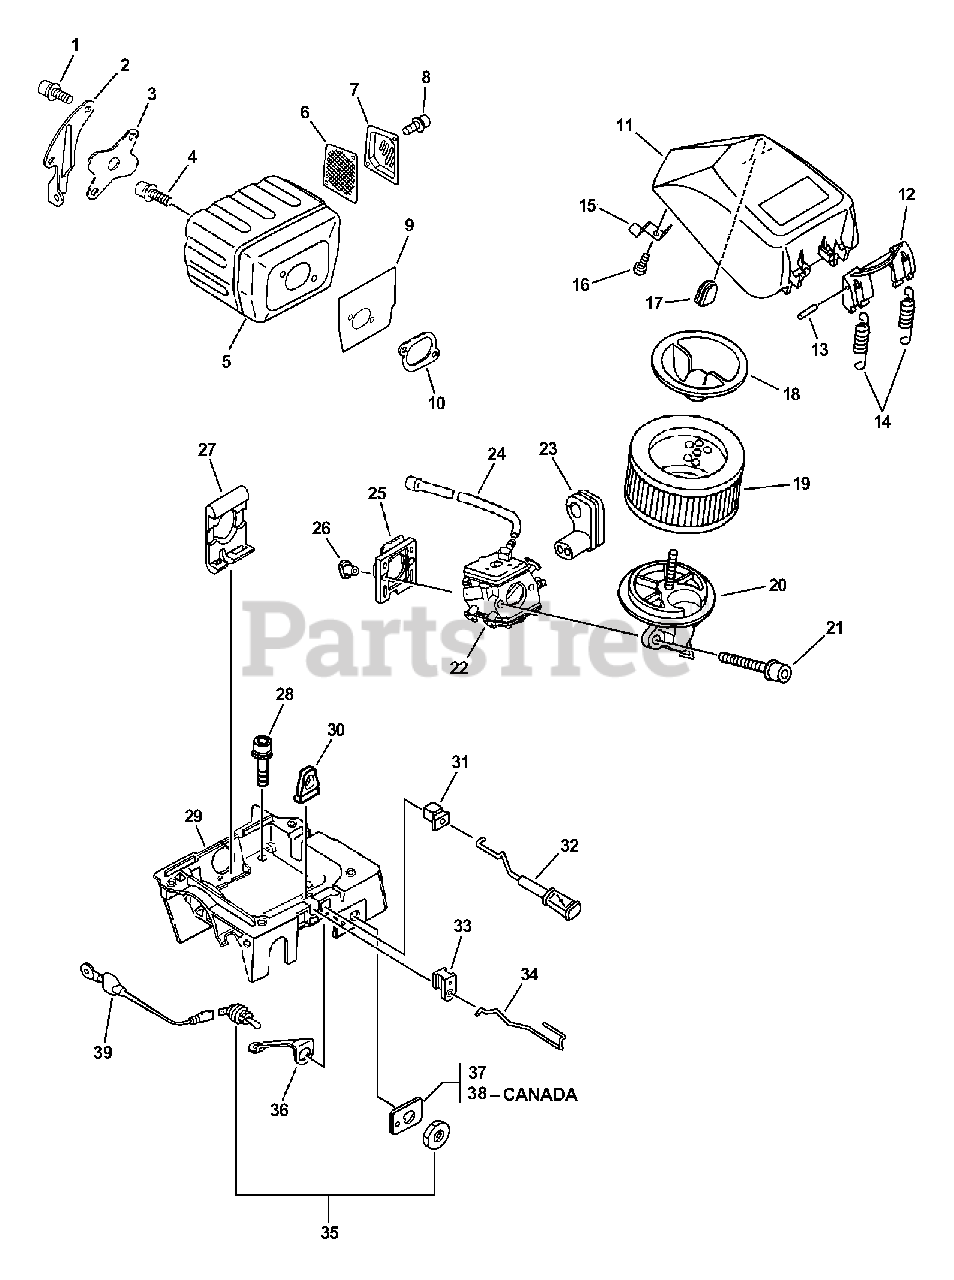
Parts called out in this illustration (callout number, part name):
1	SCREW - 5X14
2	BRACKET, MUFFLER
3	COVER, MUFFLER
4	SCREW - 5X20
5	MUFFLER
6	SCREEN, SPARK ARRESTOR
7	GUIDE, EXHAUST
8	SCREW - 4X10
9	SHIELD, EXHAUST
10	GASKET, EXHAUST
12	COVER, AIR FILTER
13	PIN - 3X12
15	SPRING, FLAT
16	SCREW - 4X10
18	COVER, AIR FILTER
19	FILTER, AIR
20	MOUNT, AIR FILTER
21	SCREW - 5X50
22	CARBURETOR
23	GROMMET
24	PIPE - IMPULSE
25	INSULATOR, INTAKE
27	BRACKET
28	SCREW - 5X20
29	CASE, CARBURETOR
30	CUSHION
32	ROD, CHOKE
33	GUIDE, THROTTLE ROD
34	ROD, THROTTLE
35	IGNITION SWITCH ASSY
36	TERMINAL - GROUND
37	LABEL - STOP
38	LABEL - SWITCH
39	LEAD - GROUND
